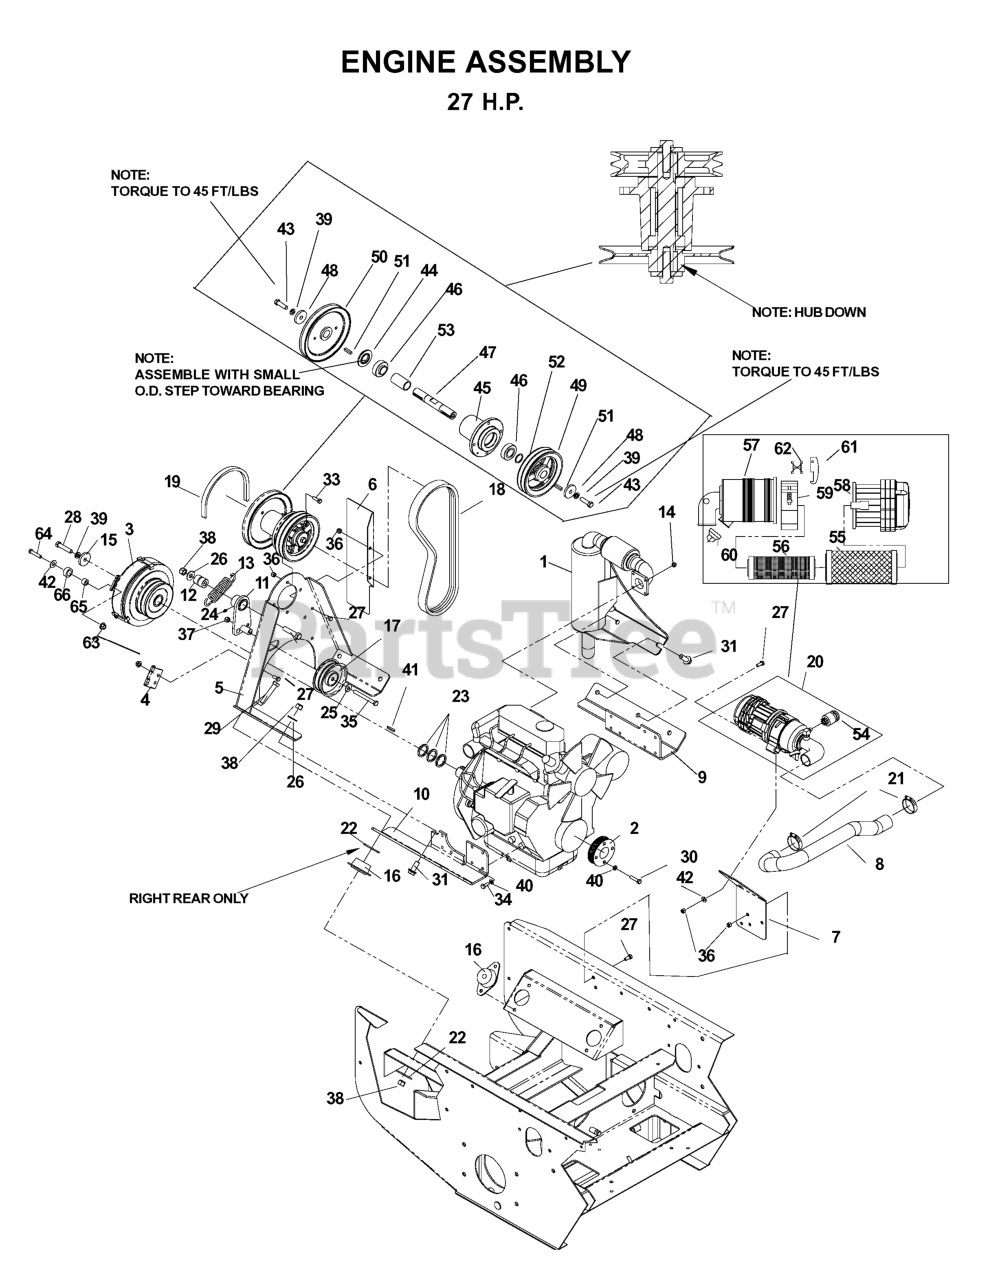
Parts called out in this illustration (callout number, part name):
1	MUFFLER NA
2	ENGINE SHEAVE
3	ELECTRIC CLUTCH
4	RESTRAINT KIT
5	JACKSHAFT MOUNT WELDMENT
6	HEAT SHIELD
7	MOUNTING BRACKET
8	AIR FILTER HOSE
9	ENGINE MOUNT-LT
10	ENGINE MOUNT-RT
11	ARM WELDMENT
14	NUT M8-1.25 STOVER
15	SPINDLE WASHER
18	BELT, PRIMARY BZ
19	ENGINE, BELT MULE
20	AIR FILTER ASSY - NON-TURBO
22	WASHER, HEAVY
23	BUSH 1-1/8 X 10 GA ZD
24	GREASE ZERK LONG
25	WASHER 3/8 SAE FLAT
26	WASHER 1/2 FLAT
27	HCS 5/16C X 3/4
28	BOLT 7/16F X 2 1/2
29	HCS 1/2C X 2 3/4
30	HTB M8-1.125 X 25MM
31	HCS 1/2C X 1 1/4 SERRATED HEAD
32	HEX SCREW 1/2-13 X 2.5" GR 5
33	HCS 5/16C X 1
35	HCS 3/8-16 X 3-1/2 GR5 ZD
36	NUT 5/16 NYLOC
37	NUT 3/8-16 NYLOC
38	NUT 1/2-13 HEX NYLOC ZD
39	WASHER 7/16 LOCK
40	WASHER.LOCK.HVY.HLCL.SPR.5/16
41	KEY 1/4 SQ X 2-1/2
42	WASHER 5/16 FLAT
43	HCS 7/16F X 1 1/2
44	COMBO SPACER
45	HOUSING, DIE CAST
46	BEARING
48	SPINDLE WASHER
51	KEY 1/4 SQ X 1 1/8
52	BUSHING.MACHINE.18.GAUGE
55	AIR FILTER
56	SAFETY ELEMENT
57	BODY - 90 DEG
58	PRECLEANER ASM
59	MOUNTING BRACKET
63	NUT 5/16C WHIZ
64	HCS 5/16C X 1 1/4
